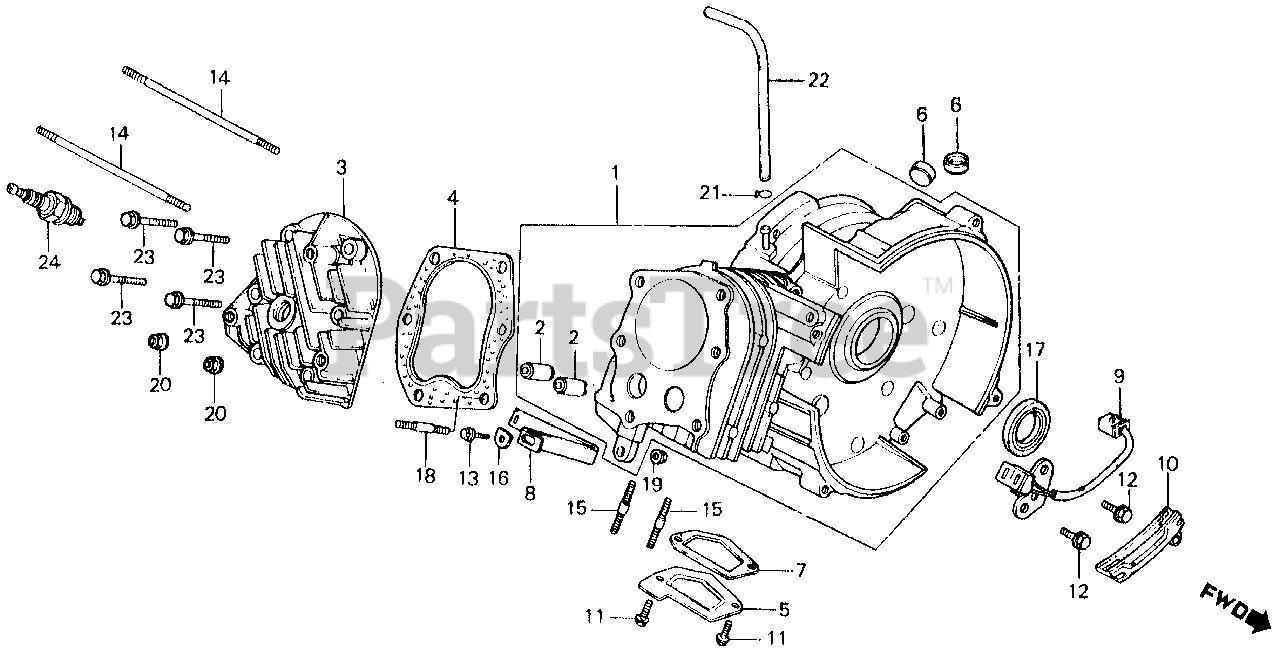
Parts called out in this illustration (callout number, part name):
2	GUIDE, VALVE
3	CYLINDER HEAD
4	GASKET, CYLINDER HEAD
5	COVER, TAPPET (NOT AVAILABLE)
6	CAP, CONNECTING ROD HOLE (NOT AVAILABLE)
7	GASKET, TAPPET COVER (NOT AVAILABLE)
8	BIMETAL, AUTOMATIC CHOKE (NOT AVAILABLE)
9	PULSER (NOT AVAILABLE)
10	COVER, PULSER
11	BOLT, FLANGE (5X10)
12	BOLT, FLANGE (5X12)
13	BOLT, FLANGE (5X16) (NA USE ALT:90007-892-000)
14	BOLT, STUD (5X85)
15	BOLT, STUD (6X28)
16	WASHER, LOCK
17	OIL SEAL (17X30X6) (NOK)
18	BOLT, STUD (6X40) (SOURCE: VINTAGE PARTS INC.)
19	NUT, HEX. (5MM)
20	NUT, FLANGE (6MM)
21	CLIP, TUBE (B8)
22	BULK HOSE, VACUUM (4.5X1000) (4.5X95)
23	BOLT, FLANGE (6X35)
24	SPARK PLUG (BPMR4A-10) (NGK)
24	SPARK PLUG (W20MPR-U10)
